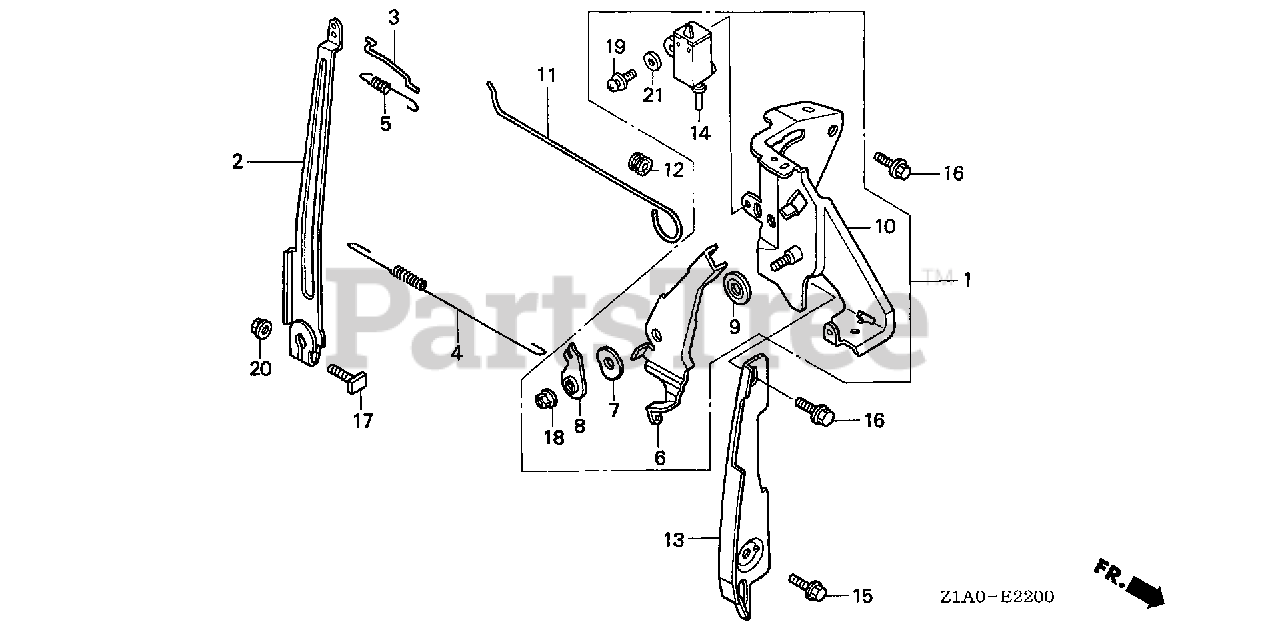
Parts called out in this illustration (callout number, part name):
1	CONTROL ASSY.
2	ARM, GOVERNOR
3	ROD, GOVERNOR
4	SPRING, GOVERNOR
5	SPRING, THROTTLE RETURN
6	LEVER, CONTROL
7	SPRING, LEVER
8	WASHER, CONTROL LEVER
9	SPACER, CONTROL LEVER
10	BASE, CONTROL
11	ROD, CHOKE CONTROL
12	GROMMET, CHOKE ROD
13	PLATE, SIDE
14	SWITCH ASSY., ENGINE STOP (N.O)
15	BOLT, FLANGE (6X12) (CT200)
16	BOLT, FLANGE (6X14)
17	BOLT, GOVERNOR ARM
18	NUT, SELF-LOCK (6MM)
19	SCREW-WASHER (4X12)
20	NUT, FLANGE (6MM)
21	WASHER, PLAIN (4MM)
